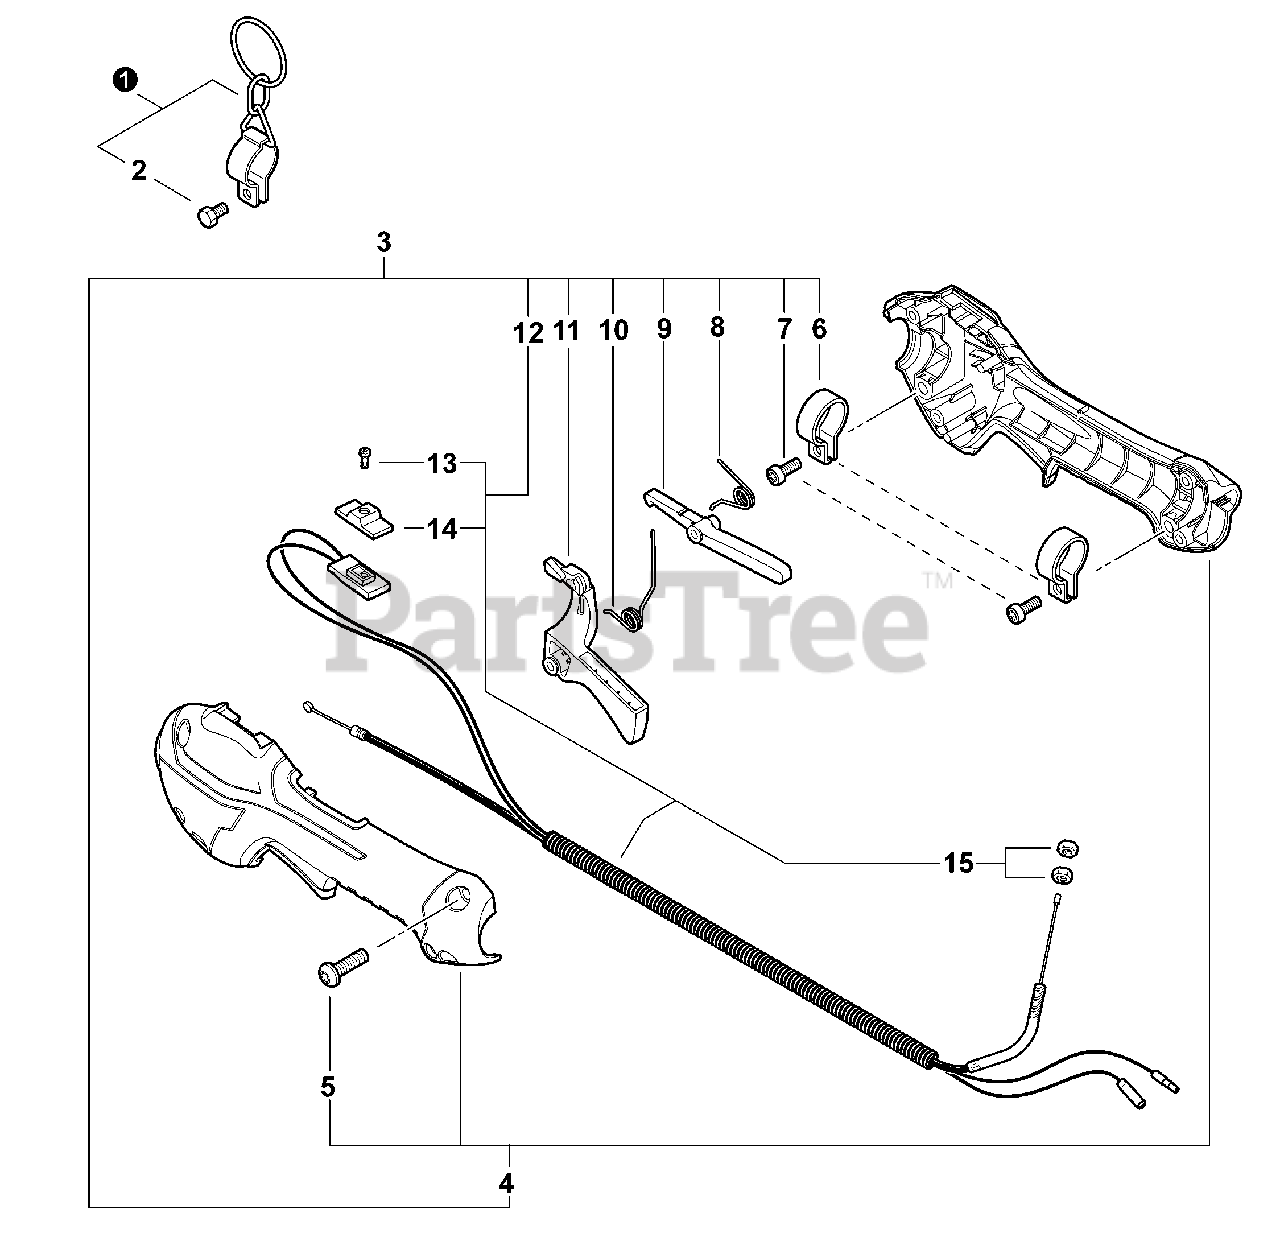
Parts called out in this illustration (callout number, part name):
1	HARNESS HANGER KIT
2	BOLT - 5X12
3	CONTROL HANDLE ASSY
4	CONTROL HANDLE KIT
5	SCREW - 5X16
7	SCREW - 5X16
8	SPRING, LOCKOUT LEVER
9	LEVER, THROTTLE LOCKOUT
10	SPRING, TRIGGER
11	TRIGGER, THROTTLE
12	CONTROL CABLE ASSY
13	SCREW - 3X10
14	KNOB, SWITCH - ORANGE
